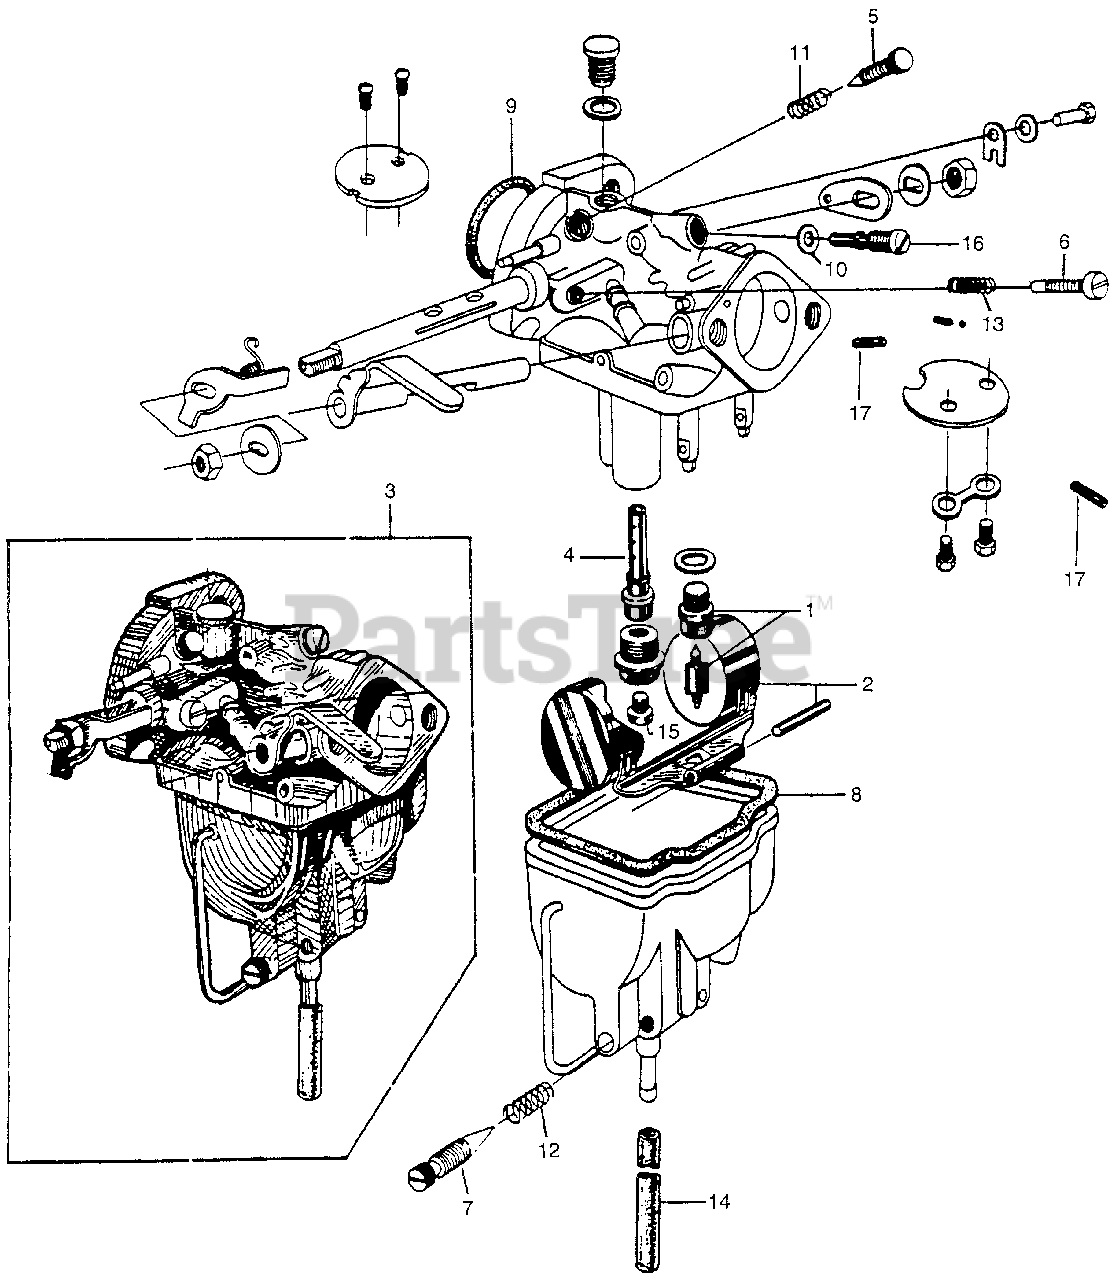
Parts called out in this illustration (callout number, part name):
1	VALVE SET, FLOAT
2	FLOAT SET
3	CARBURETOR ASSY. (NOT AVAILABLE)
4	NOZZLE, MAIN (NOT AVAILABLE)
5	SCREW, PILOT
6	SCREW, THROTTLE STOP
7	SCREW, DRAIN
8	WASHER, FLOAT CHAMBER
9	O-RING (29X2.4)
10	O-RING (2.8MM) (NOT AVAILABLE)
11	SPRING, AIR SCREW (NOT AVAILABLE)
12	SPRING, THROTTLE STOP
13	SPRING, THROTTLE STOP
14	BULK HOSE, FUEL (3.5X3000) (3.5X150)
15	JET, MAIN (#80) (NOT AVAILABLE)
15	JET, MAIN (#82) (NOT AVAILABLE)
15	JET, MAIN (#85) (NOT AVAILABLE)
15	JET, MAIN (#88) (NOT AVAILABLE)
15	JET, MAIN (#90) (NOT AVAILABLE)
16	JET, SLOW (#35) (NOT AVAILABLE)
16	JET, SLOW (#38) (SOURCE: VINTAGE PARTS INC.)
16	JET, SLOW (#40) (NOT AVAILABLE)
16	JET, SLOW (#42) (NOT AVAILABLE)
17	JET, AIR (#100)
17	JET, AIR (#120)
17	JET, AIR (#130)
17	JET, AIR (#150) (NOT AVAILABLE)
17	JET, AIR (#110)
17	JET, AIR (#140)
17	JET, AIR (#160)
17	JET, AIR (#180)
17	JET, AIR (#190)
17	JET, AIR (#200)
